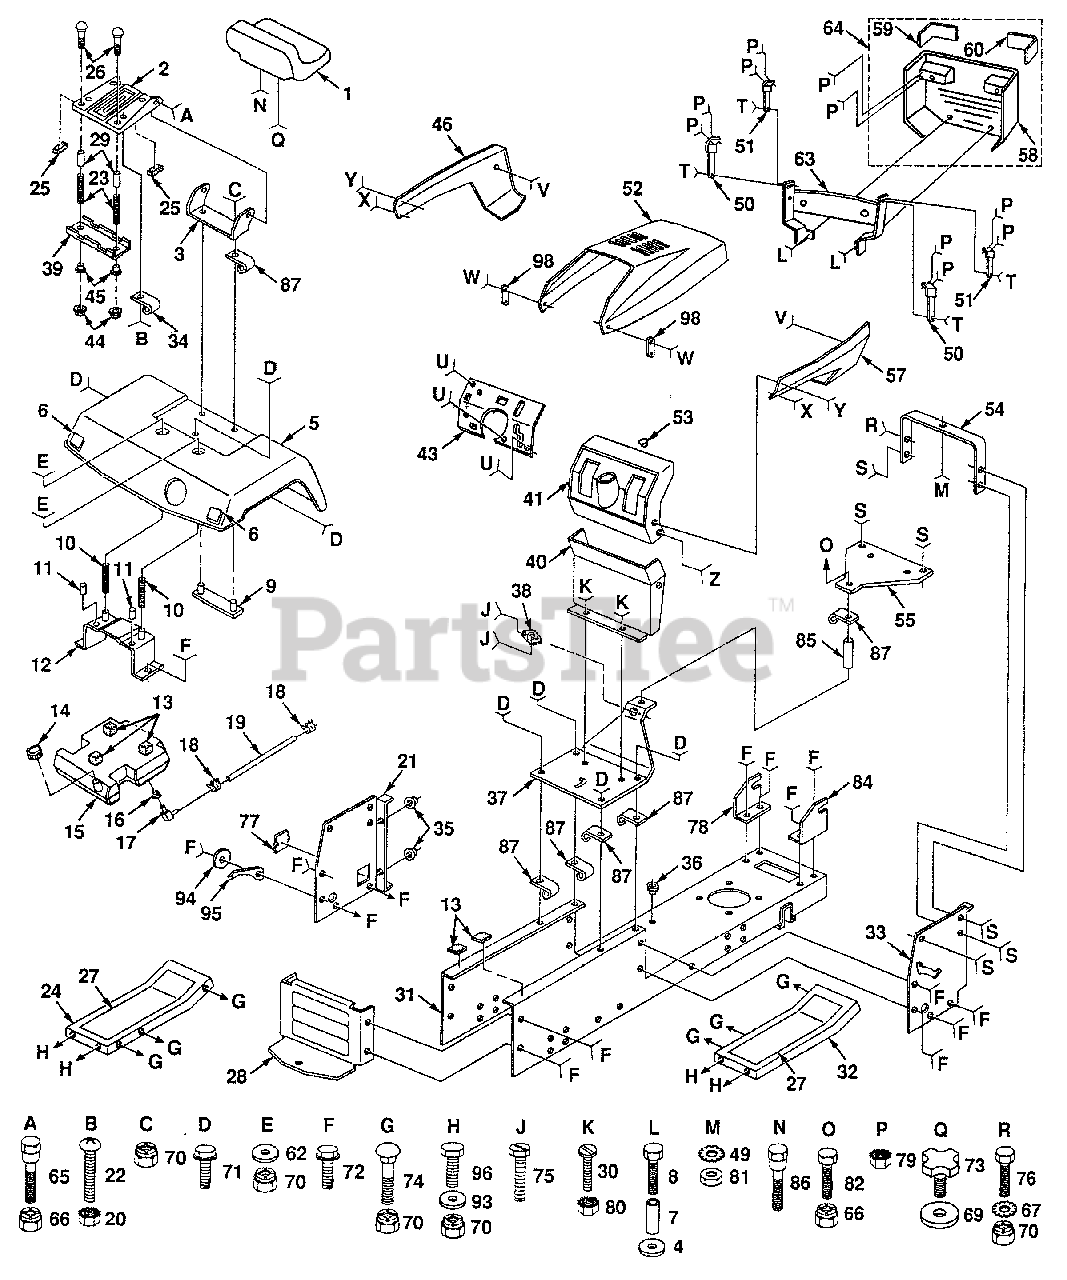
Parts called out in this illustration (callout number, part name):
1	Seat
3	Bracket, Pivot, Seat
4	Washer 9/32 x 3/4 x 16 Gauge
5	Fender
6	Reflector, Tail Light
8	Bolt, Fin, Hex 1/4 - 20 x 2-1/2
9	Strap, Fender
10	Spring, Compression
12	Bracket, Fender
13	Pad, Spacer
15	Tank, Fuel
16	Bushing
17	Stem, Tank, Fuel
18	Clamp, Hose
19	Line, Fuel
20	Nut, Keps #10
21	Panel, Dash, L.H.
22	Screw, Pan Head #10 - 32
23	Spring, Compression
24	Footrest, L.H.
25	Strip, Foam
26	Bolt, Carriage 1/4 - 20 x 1-1/4
27	Pad, Footrest
28	Drawbar
29	Spacer, Split .28 x .88
30	Screw, Mach. Cr. Threaded 5/16-18x3/4
32	Footrest, R.H.
33	Panel, Dash, R.H.
34	Clip, Insulated
35	Grommet, Split
37	Saddle
38	Bushing, Steering
39	Bracket, Switch Mount
40	Dash Assembly, Lower
41	Dash
43	Plate, Dash
44	Locknut, Hex, Large, Flange
45	Bushing, Snap
46	Panel, Side, L.H.
49	Washer, Lock, External Tooth 1/4
50	Strap Assembly, Hinge, Rear
51	Strap Assembly, Hinge, Front
52	Hood
53	Plug, Button
54	Support, Dash
55	Plate, Support, Battery
57	Panel, Side, R.H.
58	Grill
59	Lens, L.H.
60	Lens, R.H.
62	Washer 13/32 x 1 x 14 Ga.
63	Support, Grill Assembly
64	Grill Assembly
65	Bolt, Shoulder 5/16 - 18
66	Nut, Crownlock 5/16 - 18
67	Washer, Lock, External Tooth 3/8
69	Washer 17/32 x 1-3/16 x 12 Gauge
70	Nut, Crownlock 3/8 - 16
71	Screw, Hex, Washer Thrdrol. 3/8-16x1/2
72	Screw, Hex, Washer Thrdrol. 3/8 - 16 x 3/4
73	Knob, Seat 1/2"
74	Bolt, Carriage 3/8 - 16 x 3/4
75	Screw, Hex, Tap #10 - 16 x 1/2
76	Bolt, Hex 3/8 - 16 x 1
77	Cover, Access
78	Bracket Assembly L.H.
79	Nut, Hex, Keps 1/4 - 20 UNC
80	Nut, Hex, Keps 5/16 - 18 UNC
81	Nut, Fin, Hex 1/4 - 20 UNC
82	Bolt, Hex 5/16 - 18 x 2
84	Bracket Assembly, R.H.
86	Bolt, Shoulder 5/16 - 18 x .62
87	Clip, Insulated
93	Washer 13/32 x 13/16 x 12 Gauge
94	Washer, Nylon .44 x .75 x .032
95	Pointer, Height, Indicator
96	Bolt, Hex 3/8 - 16 x 3/4
98	Latch, Hood
